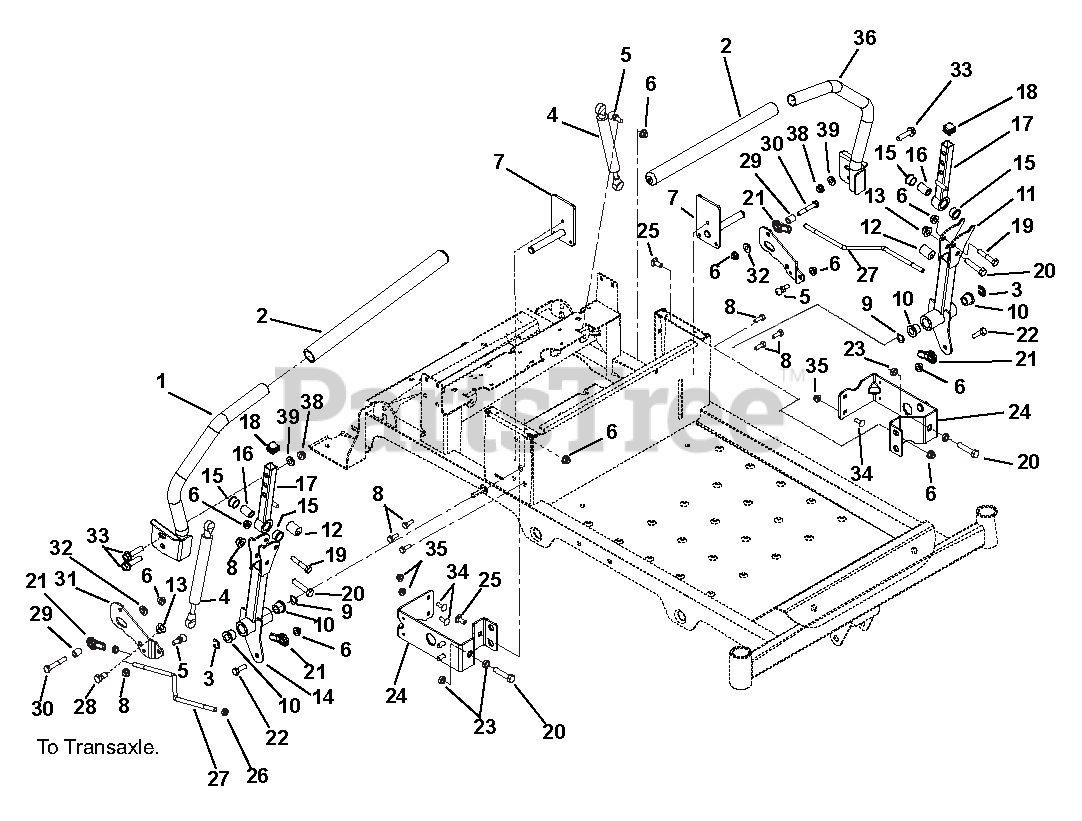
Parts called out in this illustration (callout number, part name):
1	WMT, STEERING HANDLE
2	GRIP, HANDLEBAR 15" FOAM
3	RG-RTNG-EXT .500X.042 (E)
4	DAMPER, STABILUS
5	STUD- BALL
6	@NUT-LK-NYL-FLG .31-18 YWZC
7	WMT, STEERING SHAFT
8	SCR-TAP .25-20X.50 HWH TR YWZ
9	WSHR-FL-STL 1.031X1.625X.188
10	BSHG-FLG .500X.750X.625X.937
11	WMT, LOWER CONTROL ARM
12	BSHG, ECCENTRIC .328X.750X.970
13	@NUT-LK-NYL-FLG .38-16 YWZC
14	WMT, LOWER CONTROL RH
15	BSHG-FLG, .625X.75X.450X.875
16	SPACER, .375X.625X.970 (PM)
17	WMT, UPPER CONTROL ARM
18	CAP PLUG, SQ 3/4-14-20 RIBBED
19	@BLT-HEX .31-18X1.75 GR5 YWZC
20	BLT-HEX .375-16X1.750 FTD YWZC
21	ALIGNABALL, 5/16 RH THREAD
22	@BLT-HEX .31-18X1.00 GR5 YWZC
23	NUT-HEX-JAM .375-16 YWZC
24	WMT, STEERING STOP
25	@BLT-RHDSSQNK .31-18X.75 G5YZ
26	NUT-JAM .31-24 YWZC
27	WIREFORM, STEERING LINK
28	@BLT-HEX .38-16X.75 GR5 YWZC
29	SPACER, .328X.500X.625
30	@BLT-HEX .31-18X2.00 GR5 YWZC
31	PLATE, DAMPER RH
32	BSHG-FLG .316X.430X.225X.750
33	BLT-SERHFWH .375-16X1.25 YWZC
34	@BLT-RDHDSQNK .25-20X.75 G5YZ
35	@NUT-LK-NYL-FLG .25-20 YWZC
36	WMT, STEERING HANDLE LH
37	PLATE, DAMPER (LH)
38	@NUT-LK-CTR-JAM .375-16 YWZC
39	@WSHR-FL-STL.406X.812X.065 YWZ
